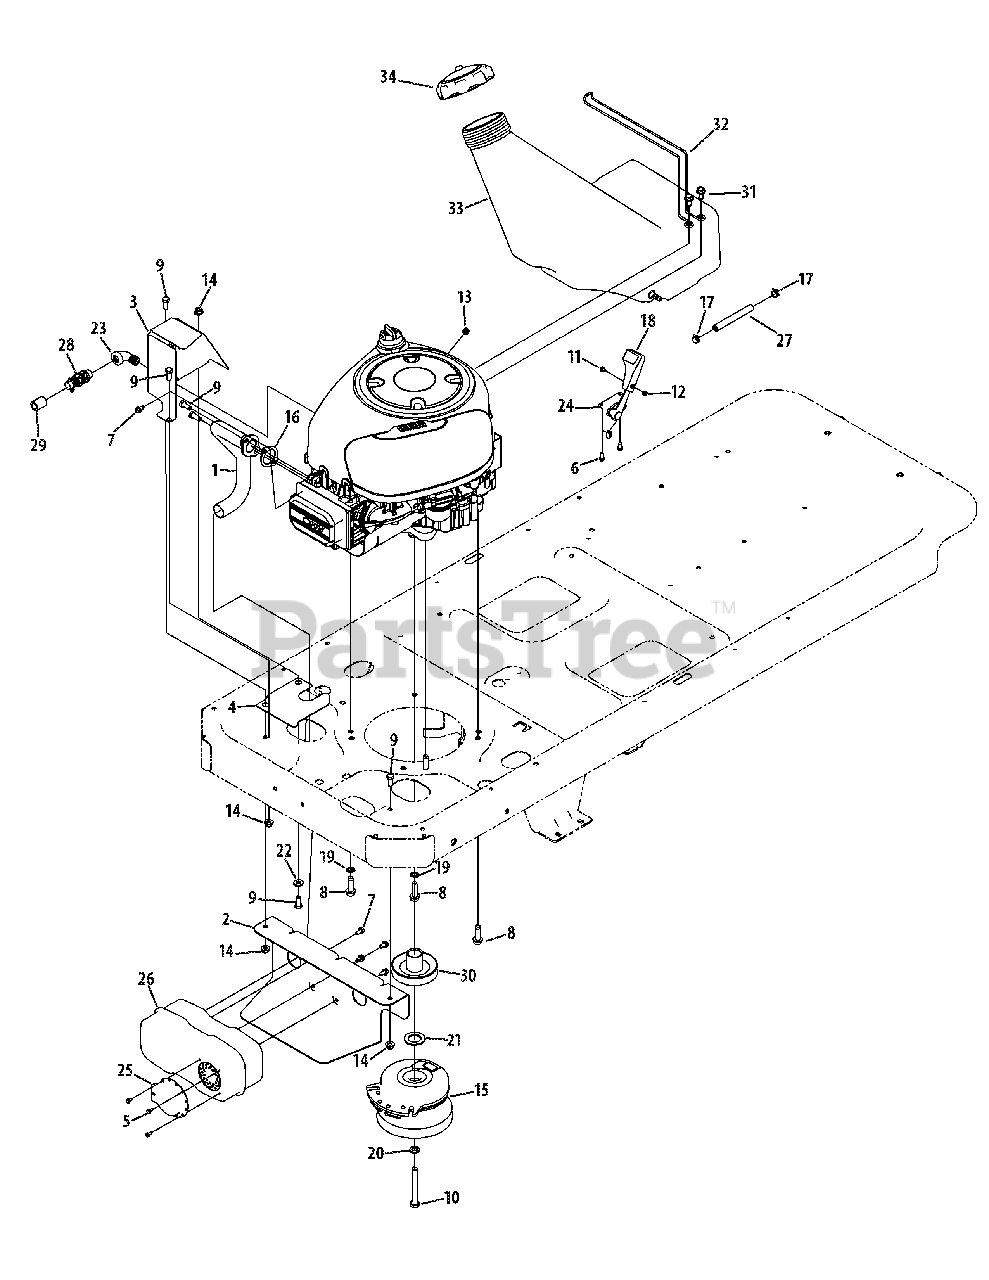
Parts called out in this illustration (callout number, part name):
1	Exhaust Tube Assembly
2	Muffler Mount Bracket
3	Muffler Heat Shield
4	Heat Shield
5	Hex Washer Screw, #8-18 x .500
6	Hex Washer Screw, #12-16 x .50
7	Hex Washer Screw, 1/4-20 x .500
8	Hex Washer Screw, 3/8-16 x 1.250
9	Hex Screw, 5/16-18 x .75
10	Hex Screw, 7/16-20 x 3.25
11	Machine Screw, #8-32 x .375
12	Hex Nut, #8-32
13	Sems Nut, 1/4-20
14	Flange Lock Nut, 5/16-18
15	Electric PTO Clutch
16	Exhaust Gasket
17	Hose Clamp, .490
18	Throttle Control Knob
19	Lock Washer, 3/8
20	Lock Washer, 7/16
21	Flat Washer, 1.031 x 1.620 x .095
22	Flat Washer, .344 x .750 x .120
23	Elbow Fitting, 3/8
24	Throttle/Choke Control Cable
25	Muffler Deflector
26	Single Inlet Muffler
27	Low Permeation Fuel Hose
28	Oil Drain
29	Oil Drain Extension Hose
30	Engine Pulley
31	Hex Washer Screw, 5/16-18 x .750
32	Tank Wire
33	Fuel Tank
34	Fuel Cap
